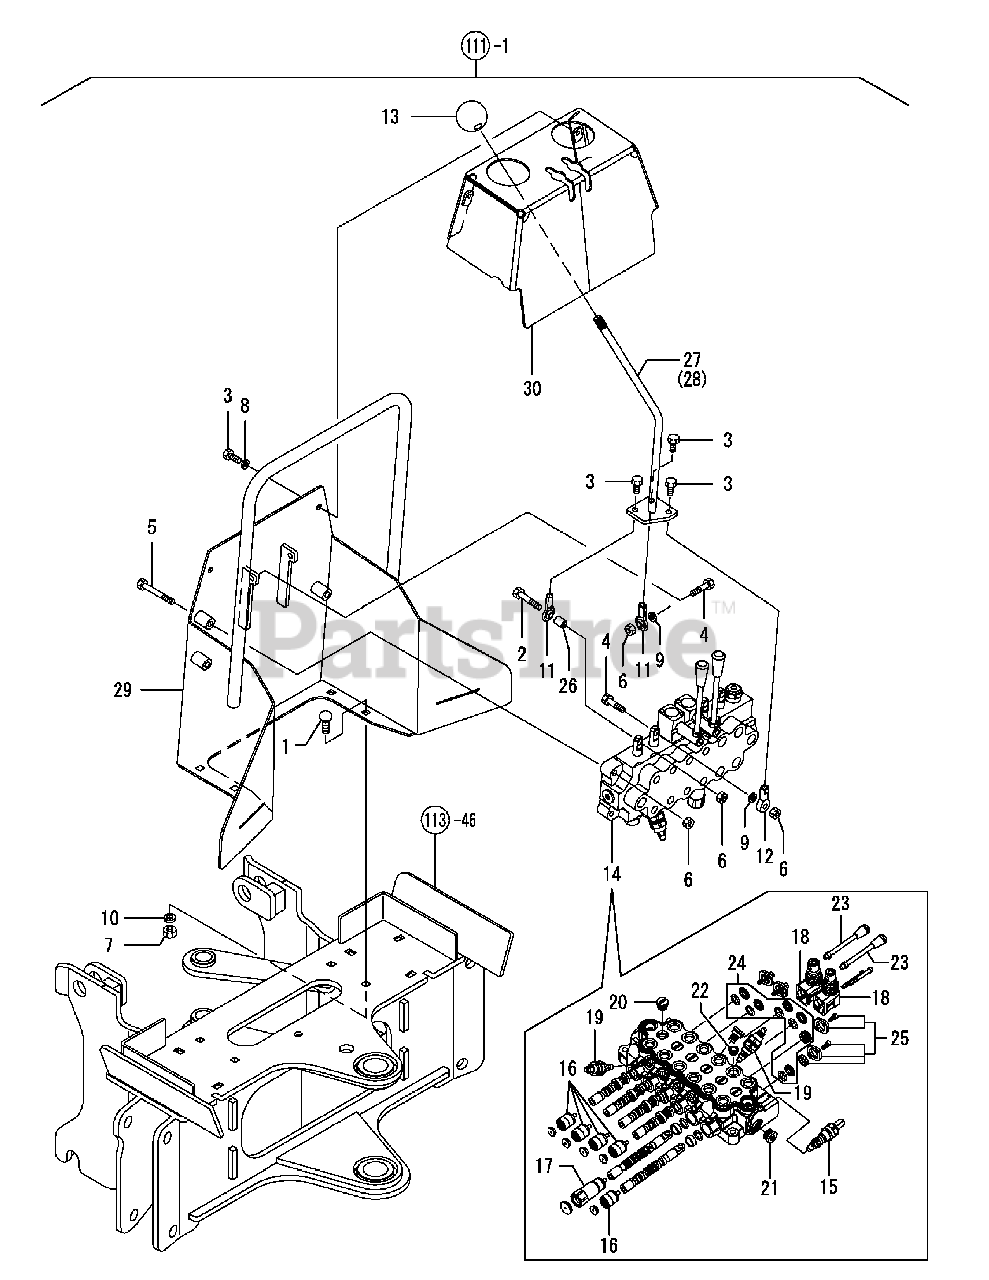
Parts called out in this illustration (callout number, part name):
1	BOLT, CARR 38X100
2	BOLT, HEX 31X175
3	BOLT, HEX 31X75
4	BOLT, HEX 31X125
5	BOLT, HEX 31X250
6	NUT, LOCK NF 31
7	NUT, LOCK NC 38
8	WASHER, LOCK 31
9	FLAT, LOCK 5/16
12	BALL JOINT, FEMALE
13	KNOB BALL BLACKK
14	VALVE, 6 SPOOL
15	MAIN RELIEF CMP
17	BOOM POSITIONER
18	STABILIZER LEVER BOX
19	RELIEF VALVE, W/P
20	VALVE, LOAD CHECK
21	PLUG, 3/4-16UNF
23	STABILIZER HANDLE
24	SEAL KIT, C/T VALVE
25	WIPER RETAINING KIT
27	RH CONTROL HANDLE
28	LH CONTROL HANDLE
29	CONTROL TOWER M ASSY
30	VALVE COVER M ASSY
